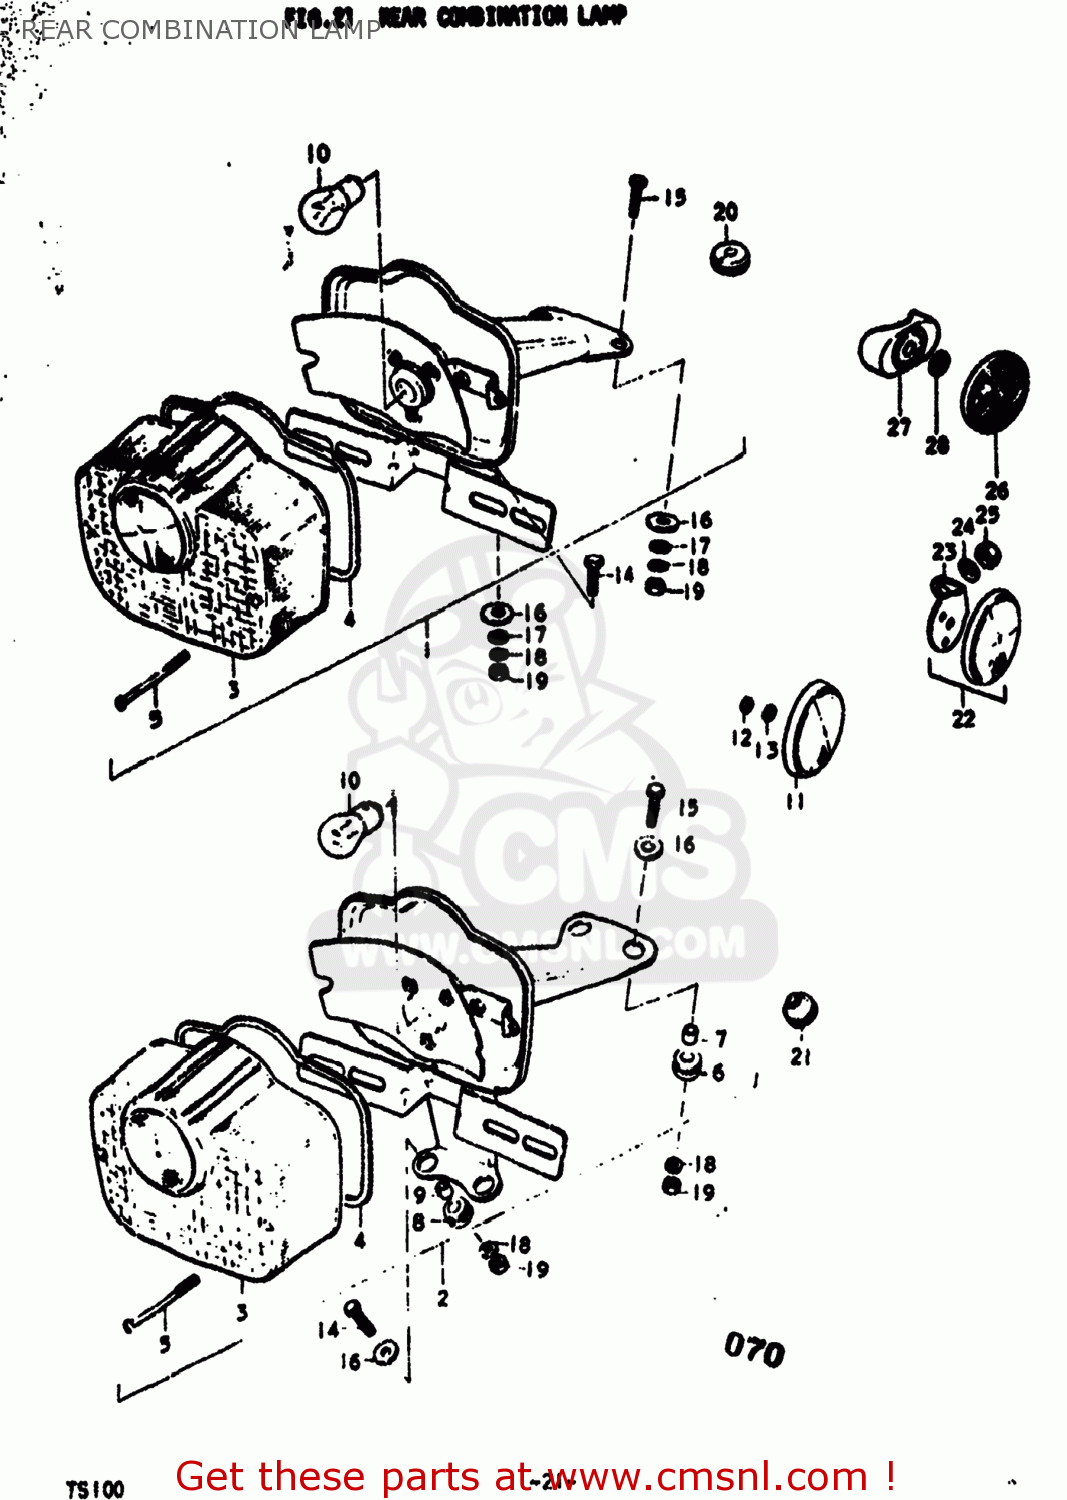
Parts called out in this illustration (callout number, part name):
1	LAMP ASSEMBLY,REAR COMBINATION
2	LAMP ASSEMBLY,REAR COMBINATION
3	LENS,REAR COMBINATION LAMP
4	GASKET (NAS)
5	SCREW
6	CUSHION
7	SPACER,REAR COMBINATION LAMP
8	CUSHION
9	SPACER,REAR COMBINATION LAMP
10	BULB(6V32/3CP,STANLEY)
11	REFLECTOR,REFLEX
12	NUT
13	LOCK WASHER
14	BOLT
15	BOLT
16	WASHER
17	WASHER 6MM
18	LOCK WASHER
19	NUT
20	GROMMET
21	GROMMET
22	REFLEX REFLECTOR ASSEMBLY
23	SPACER
24	LOCK WASHER
25	NUT
26	REFLEX REFLECTOR ASSEMBLY
27	SPACER
28	WASHER (6.5X20X1.2)
